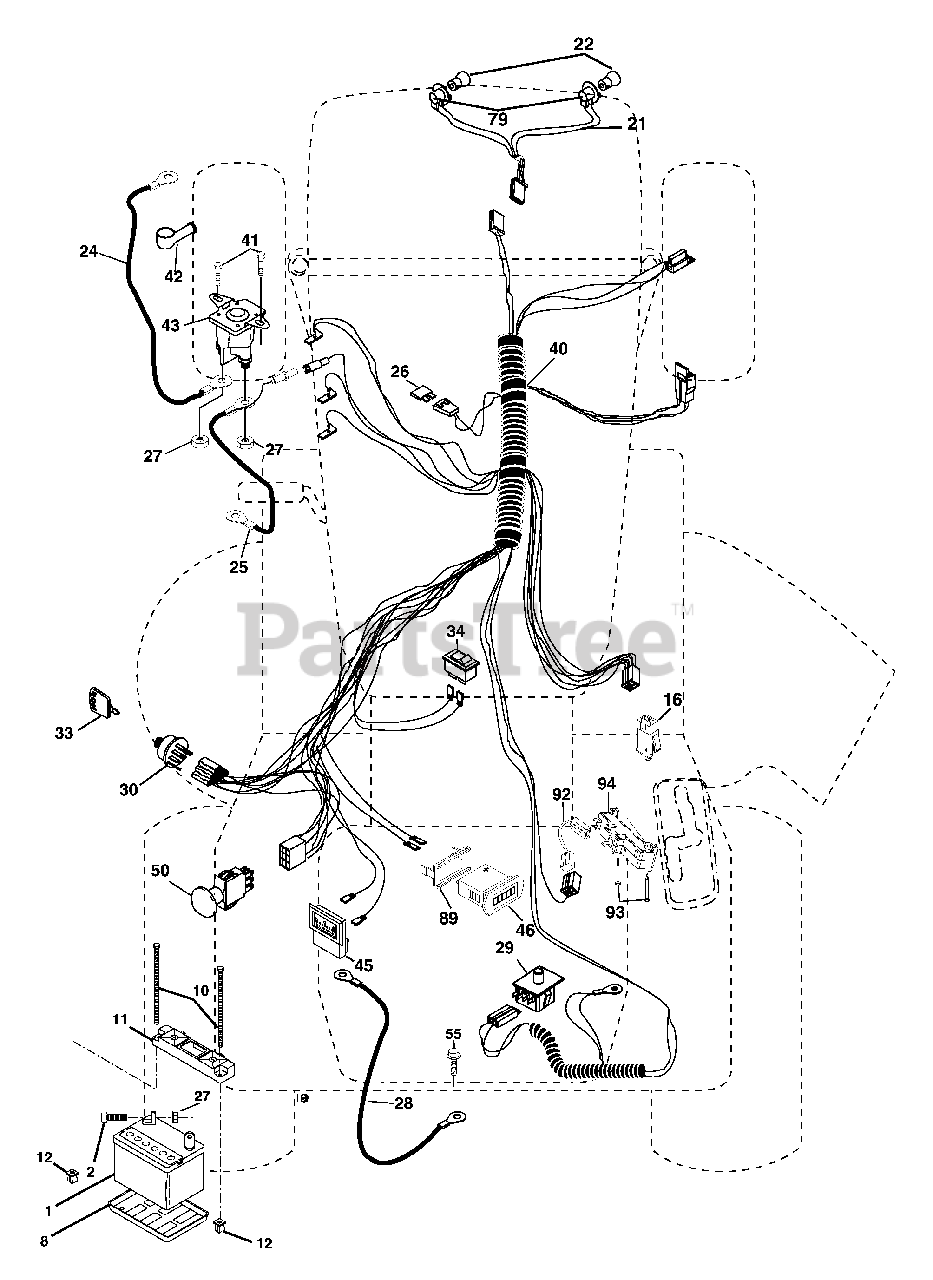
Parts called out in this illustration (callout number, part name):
1	Battery
2	Bolt Hex Hd 1/4-20 unc x 3/4
8	Tray, Battery
10	Bolt, BTR FRT 1/4-20 x 7.5
11	Hold Down Battery, Front
12	Nut, Push, Nylon
16	Switch Interlock Push-In
21	Harness Asm Light W/Bulbs
22	Bulb Light
24	Cable Battery
25	Cable Battery wire
26	Fuse
27	Nut Keps Hex 1/4-20 unc
28	Cable Ground
29	Switch Seat
30	Switch Ign
33	Key Ign
34	Light Switch
40	Harness Ign.
41	Bolt Blk Fin Hex 1/4-20 x 1/2
42	Cover Terminal Red
43	Solenoid
46	Hourmeter Snap-In
48	Ammeter Adaptor
50	Switch, PTO
55	Screw Thdrol 5/16-18 x 1/2
79	Bulbholder
89	Bracket Snap-In Hourmeter
92	Harness Pigtail Reverse Switch
93	Screw Plastite 10-14 x 2.0
94	Module Reverse ROS
